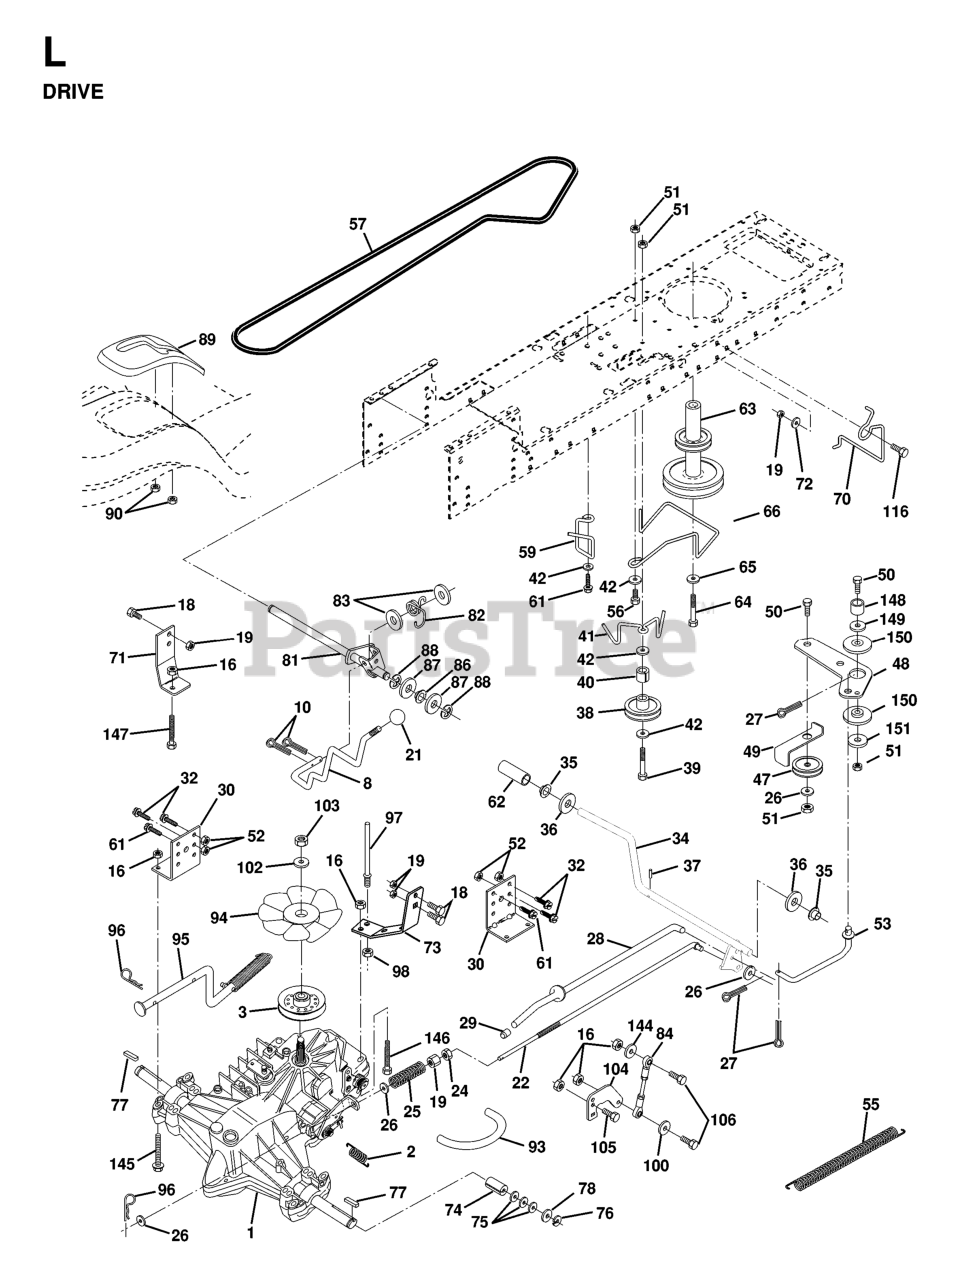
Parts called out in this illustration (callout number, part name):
1	TRANSAXLE ASSEMBLY
2	SPRING BRAKE
3	PULLEY, TRANSAXLE
8	ROD SHIFT FENDER
10	PIN COTTER
15	BOLT HEX 5/16-18 GR 5
16	NUT.71038.31-18.HEX.NYLOCK
19	NUT
21	KNOB.DUCKHEAD.1/2
22	ROD BRAKE HYDRO
24	NUT
25	SPRING ROD LT
26	WASHER
27	COTTER PIN
28	ROD BRAKE PARK LT
29	PLUNGER CAP
30	BRACKET TRANSAXLE
32	BOLT
34	SHAFT, FOOT PEDAL
35	BEARING.NYLON
37	DRIVE PIN
38	PULLEY.IDLER.FLAT
41	KEEPER, BELT IDLER
42	WASHER
47	IDLER PULLEY
48	BELLCRANK, CLUTCH
49	RETAIN BELT
50	BOLT
52	LOCKNUT
53	LINK, CLUTCH LT
55	SPRING, RETURN LT
59	KEEPER CENTER SPAN
61	SCREW
62	COVER, PEDAL (1 2)
64	REPL BY 871 17 07-64
65	LOCKWASHER
66	BELT KEEPER
70	KEEPER BELT ENG
71	STRAP LH TORQUE
72	WASHER
73	STRAP TORQUE RH HYDRO
74	SPACER SPLIT
77	SQUARE KEY
82	SPRING,TORSION
83	WASHER
89	SHIFT CONSOLE
90	NUT.PUSH.3/16
91	BOLT.FIN HEX 5/16-18UNC X2 1/4
92	HEX BOLT
93	LINE FUEL HYD 4"
94	FAN 7" HYDRO
95	CONTROL ARM, BYPASS HYDRO
96	RETAINER M
97	KEEPER BELT RH
100	WASHER M
103	NUT.HEX.1/2-20
104	CONTROL ARM
106	BOLT.5/16-18X1-1/4 FULL.THREAD
116	BOLT
149	SPACER RETAINER
150	BUSHING NYLON COLLERED
151	WASHER 12/32X2X10GA
